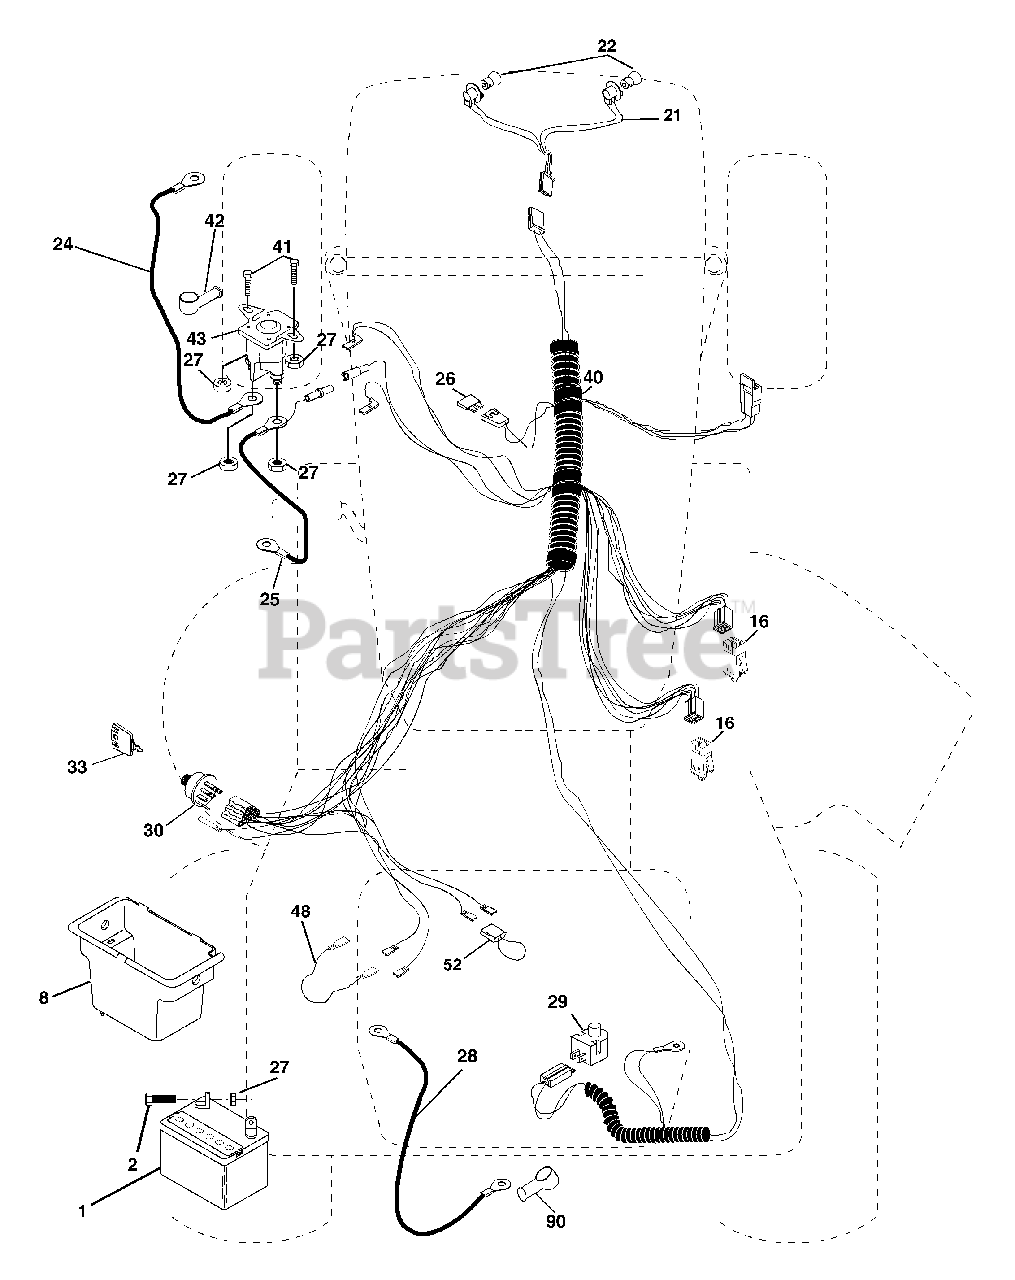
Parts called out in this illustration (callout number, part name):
1	Battery
2	Bolt Hex Hd 1/4-20 unc x 3/4
8	Box Battery
16	Switch Interlock
21	Harness Asm Light W/4152j
22	Bulb Light #1156
24	Cable Battery 6 Ga. 11"red
25	Cable Battery
26	Fuse 20 AMP
27	Nut Keps Hex 1/4-20 unc
28	Cable Ground 6 Ga. 12"black
29	Switch Plunger Nc Gray
30	Switch Ign
33	Key Ign
40	Harness Ign
41	Bolt Blk Fin Hex 1/4-20
42	Cover Terminal Red
43	Solenoid
48	Adapter Ammeter
52	Protection Wire Loop
90	Cover Terminal Battery
